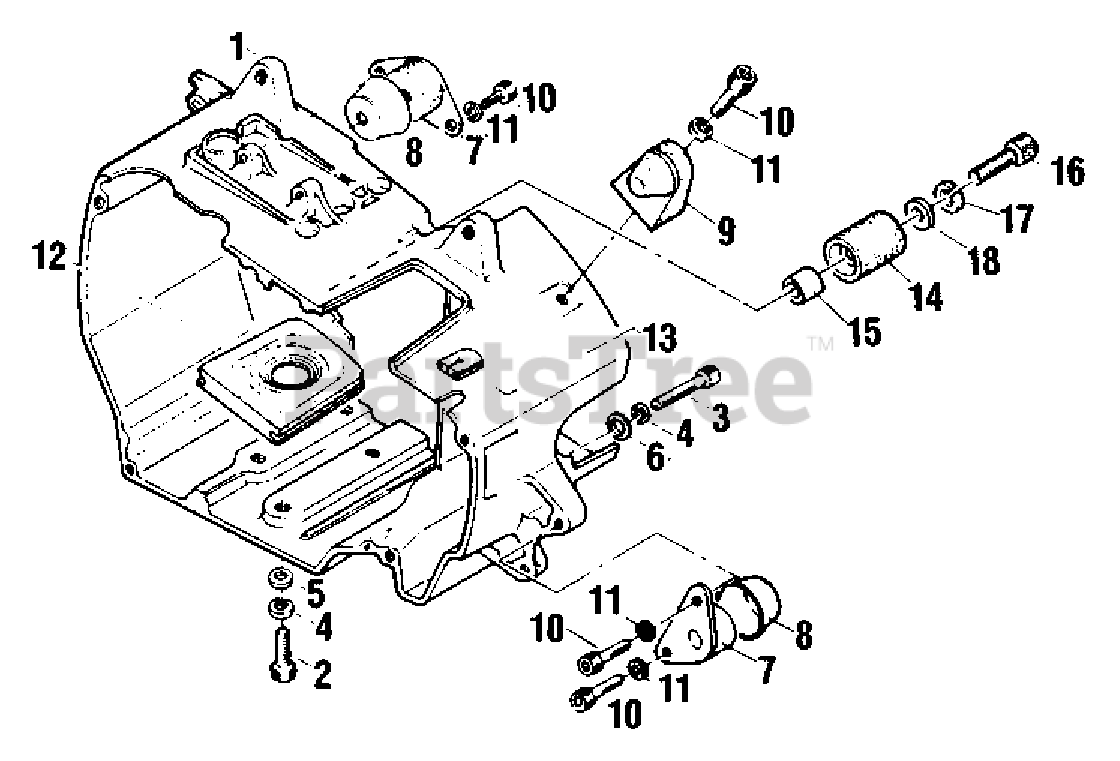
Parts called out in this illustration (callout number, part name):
1	CASE, ENGINE
2	SCREW - 5X18
3	SCREW - 5X25
4	LOCKWASHER - 5
5	WASHER - 5
6	WASHER
7	MOUNT
8	HOLDER, MOUNT
9	CUSHION, SIDE
10	SCREW - 5X12
11	LOCKWASHER - 5
12	SEAL
13	GROMMET
14	CATCHER, CHAIN
15	BUSHING
16	SCREW - 5X25
17	LOCKWASHER - 5
18	WASHER
